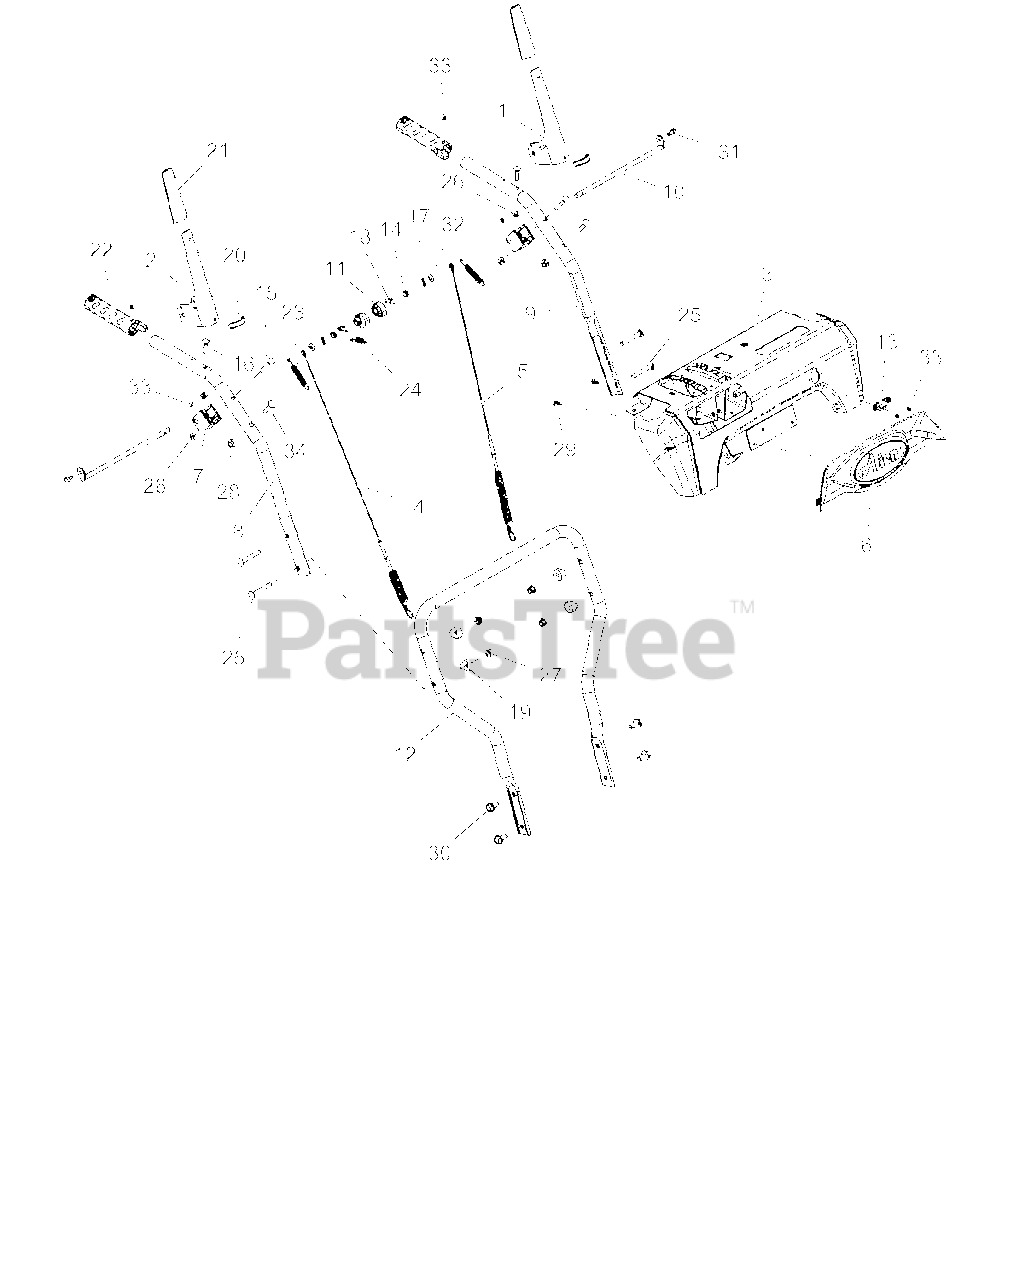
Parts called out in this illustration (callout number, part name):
1	LEVER, CLUTCH-LH
2	LEVER, CLUTCH-RH
3	CONTROL PANEL W/DECAL FRIC-QT
4	CABLE, AUGER (DELUXE & PRO)
5	CABLE, UPPER TRACTION
6	BEZEL, DASH-ARIENS LG DASH
7	BLOCK, CLUTCH PADDLE
8	HANDLEBAR, UPPER - RH
9	HANDLEBAR, UPPER - LH
10	ROD, PADDLE MOUNT - PRO
11	CAM, INTERLOCK
12	HANDLEBAR, LOWER - DELUXE
13	GROMMET, CABLE, QUICK TURN 2
14	BUSHING, POLYLINER-.38 SNAPIN
15	BLT-RDHDXLSQNK .25-20X2.0 G5YZ
16	BLT-RDHDXLSQNK.25-20X1.25 G5ZC
17	PIN-HAIR INT .06X.18X.77
18	PIN, SPRING CLIP
19	SPACER, HANDLEBAR
20	EDGING, CLUTCH PADDLE - 2.00"
21	SLEEVE, CLUTCH PADDLE-GRAY
22	GRIP,HEATED HANDLE-GRAY
23	SPRING, EXTENSION
24	SPRING-EXT .047X.438X1.45
25	@BLT-RDHDSQNK .31-18X2.25 G5YZ
26	@NUT-LK-CTR-FLG .25-20 YWZC
27	@NUT-LK-NYL-FLG .31-18 YWZC
28	@NUT-LK-TOP-FLG .31-18 YWZC
29	SCR-TAP #10X.50 BOSS INDHXHD
30	BLT-SERHFWH .38-16X.75 YWZC
31	SCR-TAP .25-20X.50 HWH TR YWZ
32	@WSHR-FL-STL.281X.62X.065 YWZC
33	RVT-POP #43 .125X.313 STL ZINC
34	@BLT-RDHDSQNK .31-18X1.50 G5YZ
